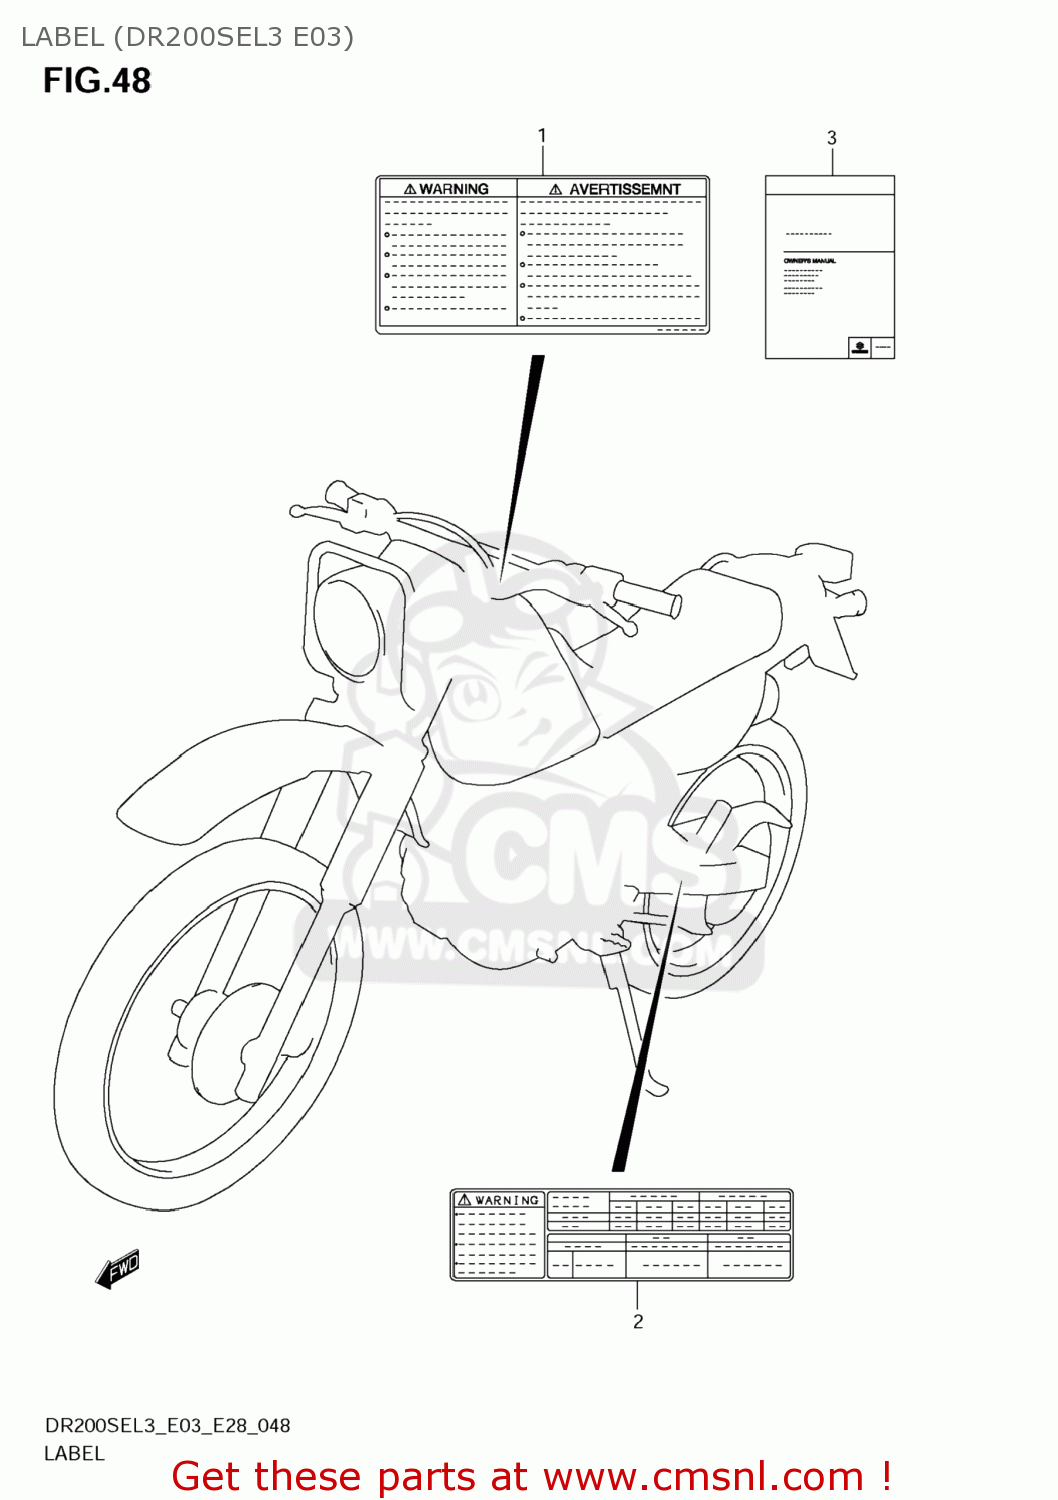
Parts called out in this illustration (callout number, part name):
1	LABEL,GENERAL WARNING
2	LABEL,TIRE INFORMATION
3	MANUAL,OWNER'S
